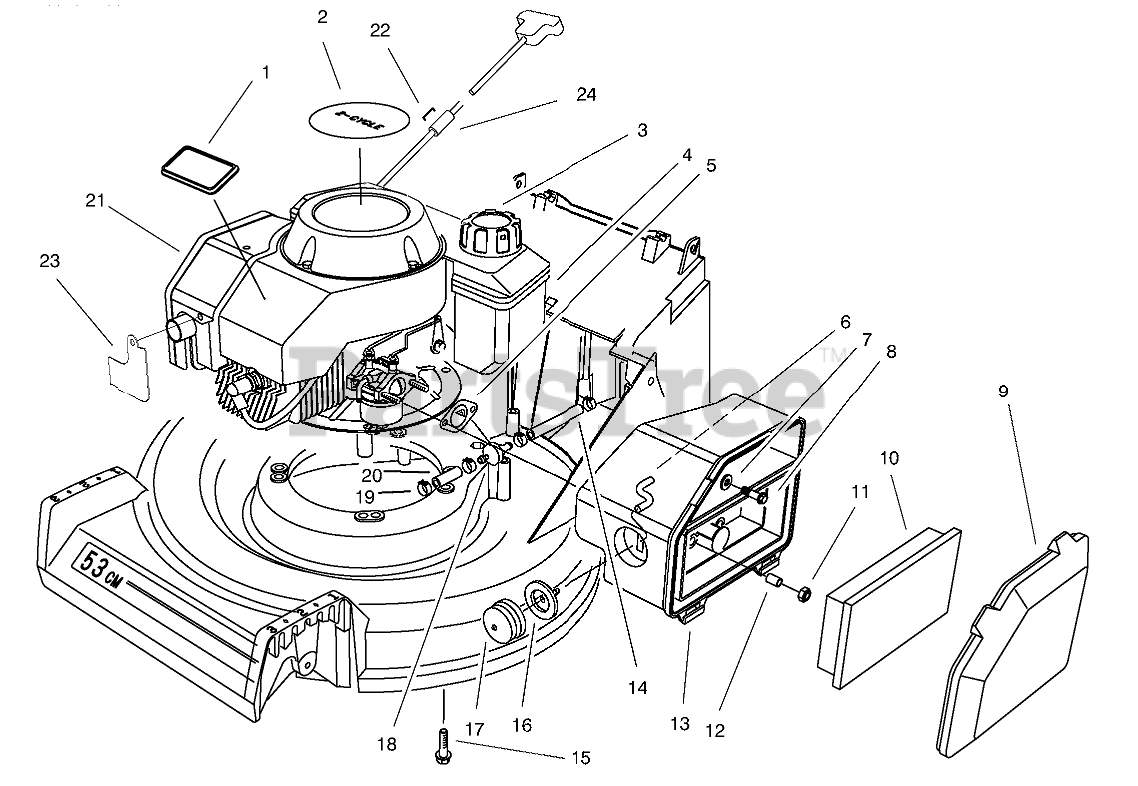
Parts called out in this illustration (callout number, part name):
1	TORO LOGO PLT
2	DECAL- 2 CYC RECOIL
3	GAS CAP ASM
4	FUEL TANK ASM
5	GASKET-AIR CLEANER
6	HOSE-PRIMER
7	WASHER-FLAT
8	SCREW-HH
9	COVER-AIR CLEANER
10	ELEMENT-AIR CLEANER
12	SPACER
13	BODY-AIR CLEANER
14	HOSE-FUEL
15	Bolt-Engine
16	BODY-PRIMER
17	BULB-PRIMER
18	FILTER-FUEL
19	CLAMP-FUEL LINE
20	HOSE-FUEL
21	ENGINE ASM - ZS 2 CYCLE
22	Staple
23	EXTENSION-MUFFLER GUARD
